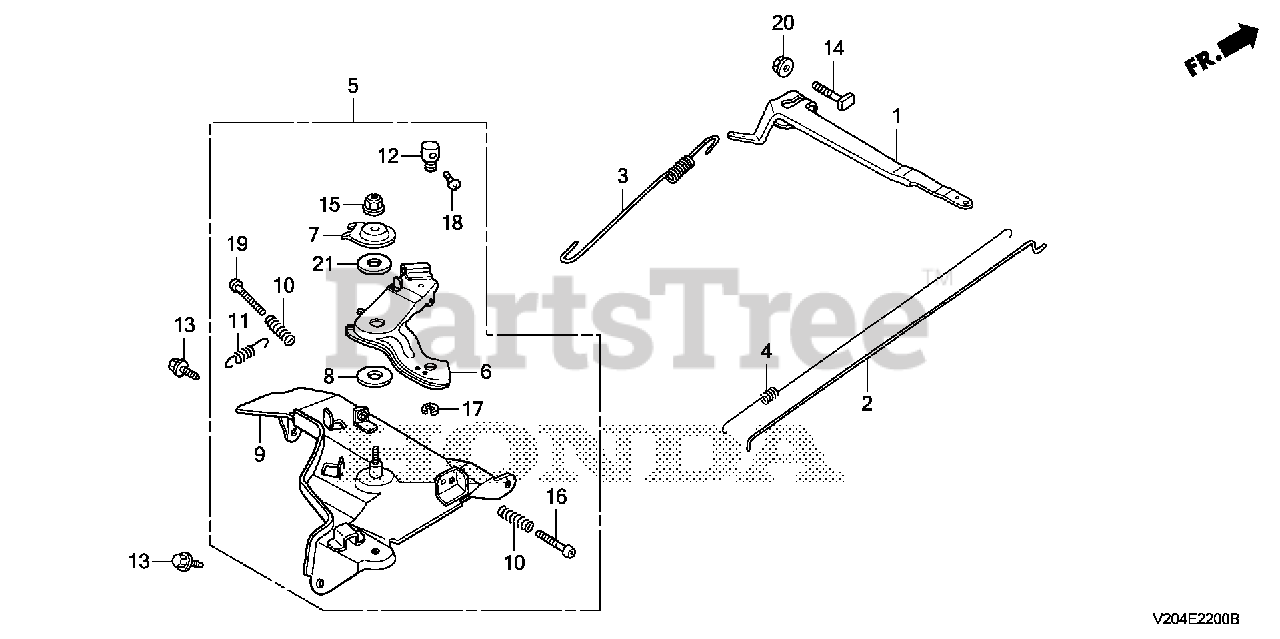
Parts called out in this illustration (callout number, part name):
1	ARM, GOVERNOR
2	ROD, GOVERNOR
3	SPRING, GOVERNOR (L=145.0MM) (WIRE DIAMETER 1.0MM)
4	SPRING, THROTTLE RETURN
5	CONTROL ASSY. (COO)
6	LEVER, CONTROL
7	WASHER, CONTROL LEVER
8	SPACER, CONTROL LEVER
9	BASE, CONTROL
10	SPRING, CONTROL ADJUSTING
11	SPRING, CABLE RETURN
12	HOLDER, CABLE
13	BOLT, FLANGE (6X12) (CT200)
14	BOLT, GOVERNOR ARM
15	NUT, SELF-LOCK (6MM)
16	SCREW, PAN (5X25)
17	CIRCLIP (5MM)
18	SCREW, PAN (4X6)
19	SCREW, PAN (5X28)
20	NUT, FLANGE (6MM)
21	SPRING, LEVER
